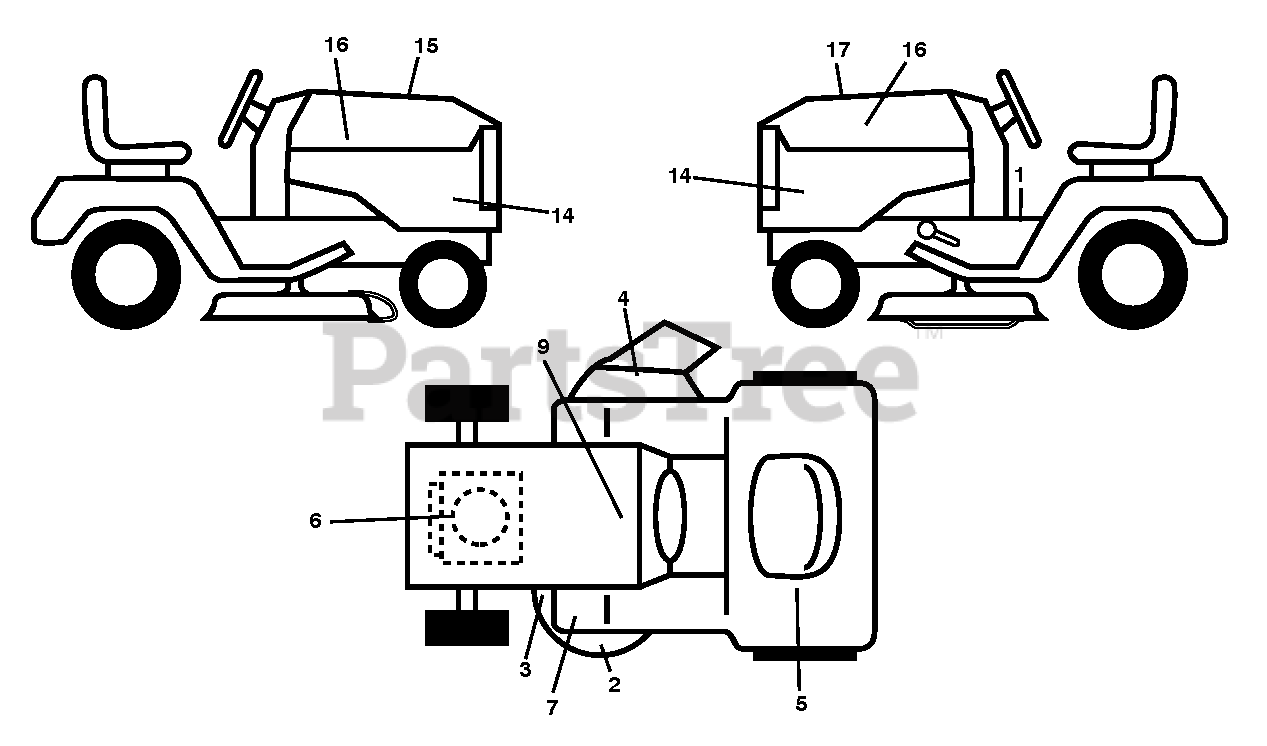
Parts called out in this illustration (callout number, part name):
1	DECAL.FENDER.WARNING
2	DECAL, NO STEP
3	DECAL.MOWER.SCH.48/54
4	DECAL, CAUTION
5	DECAL.WARN.RESERVE.FUEL
6	DECAL.ENGINE.BS27.ENDU.2794718
7	DECAL.PEDAL.HUSQ.CROWN
9	DECAL BTRY SYMBOLS
14	Decal, Side Panel HUSQGT2 GTH27V48LS
15	DECAL.WARNING.CUST.RESP.E85.
16	RP.DECAL.BADGE.170MM.TEXTLOGO
17	Decal, Replacement BSM44 ENDR 48F G730
